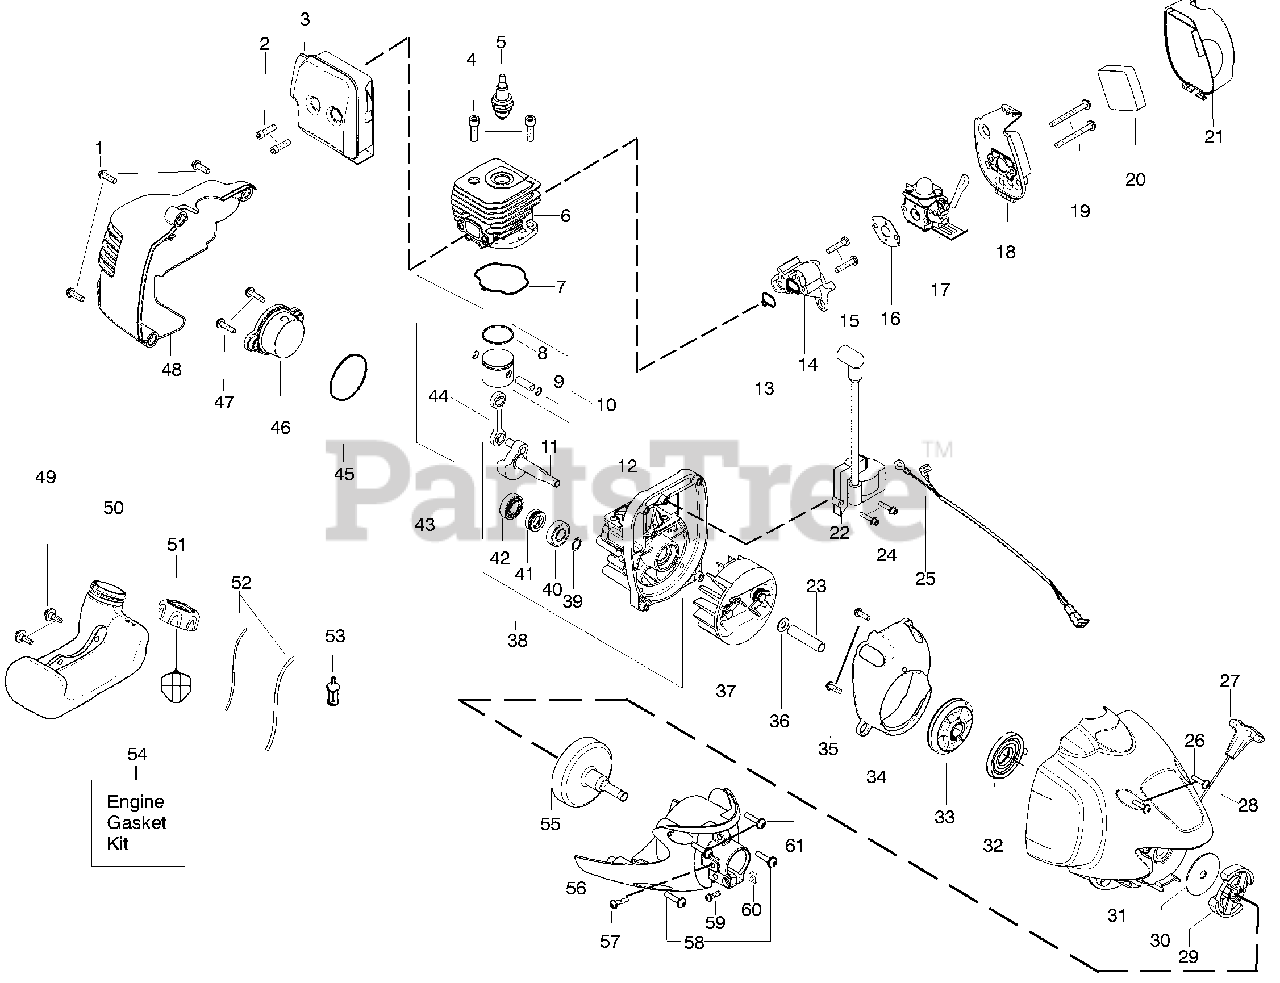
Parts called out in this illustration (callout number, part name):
2	BOLT MUFFLER
3	ASSY MUFFLER SHIELD
5	PLUG-SPARK (RCJ-6Y)
6	CYLINDER MACHINED 25CC LO
8	RING PISTON
9	WRIST PIN RET.
10	PISTON KIT
11	ASSY CRANKSHAFT
12	ASSY CRANKCASE
14	ADAPTOR CARBURETOR
17	KIT CARB ASSY
18	BASE AIR BOX PP GOLD
20	AIR FILTER
21	COVER AIR BOX FE
22	%MODULE IGNITION
23	SPACER FLYWHEEL
25	LEAD WIRE ASSEMBLY
27	HANDLE STARTER BLK
28	KIT ROPE
29	ASSEMBLY CLUTCH
30	WASHER-CLUTCH
31	HSG FAN W/EYELET PP GOLD
32	SPRING STARTER SA
33	KIT STARTER PULLEY
34	BAFFLE FAN
36	WASHER CLUTCH
37	ASSY FLYWHEEL
38	ASSY CRANKCASE & CRANKSHAFT
39	RETAINING RING
40	OUTER BEARING
42	BEARING
43	PISTON KIT
44	KIT-CONN ROD ASSY
46	ASSY REAR PLUG
48	SHROUD REAR BLACK
49	SCREW FUEL TANK RETAINER
51	FUEL CAP ASSY
53	FUEL PICK-UP ASSY
54	KIT GASKET 25CC
55	ASSY CLUTCH DRUM W/ADPT
56	ASSY CLUTCH COVER
58	SCREW-10-24 X 1" (TAP.)
59	SCREW 12-24 X 5/8
60	NUT SQUARE 12-24
